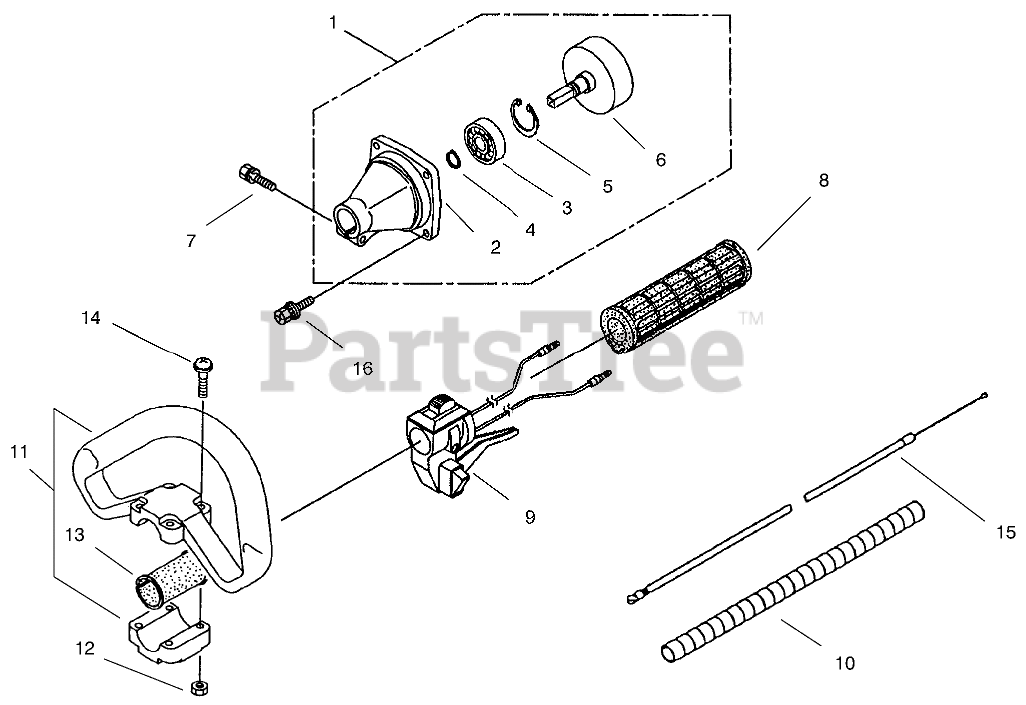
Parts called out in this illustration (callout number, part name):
1	Clutch Case Asm (Incl. Ref. # 2-6)
2	CLUTCH HOUSING
3	BEARING
4	RETAINING RING
5	RING - SNAP, C-SHAPED 32
6	CLUTCH BELL
9	THROTTLE AND SHUTOFF ASSY
10	DRIVE SHAFT LINER
11	HANDLE - LOOP
12	NUT M5
13	VIBRATION ISOLATOR
14	SCREW
15	THROTTLE WIRE
